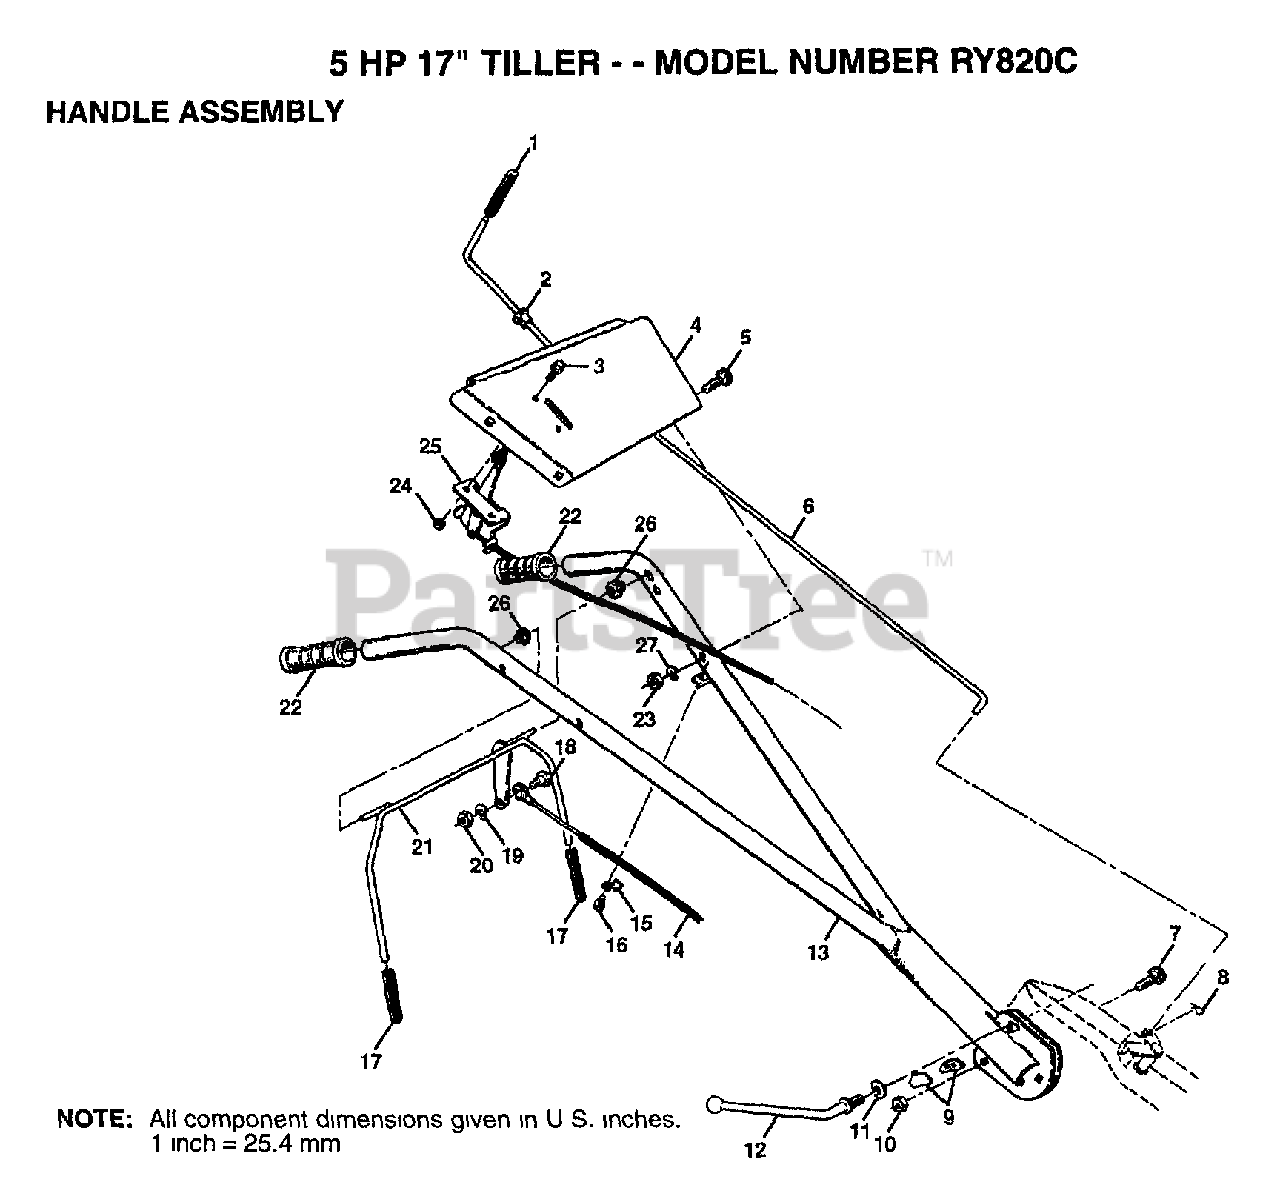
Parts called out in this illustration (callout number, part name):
1	GRIP TI
2	BUSHING
3	SCREW
4	HANDLE BRACKET
5	BOLT CARRIAGE CRT
6	ROD SHIFT CRT
7	BOLT D
8	RETAINER M
9	LOCK CRT
10	LOCKNUT
11	WASHER CRT
12	LEVER LOCK CRT
14	CABLE.CLUTCH.CRT
15	CONDIUT CLIP T
17	GRIP BAR CRT
18	SHOULDER BOLT ST
19	LOCKWASHER
21	HANDLE BAR CRT
22	GRIP HDLE NUBBED
23	NUT
25	"CONT,THROTTLE"
27	LOCKWASHER
